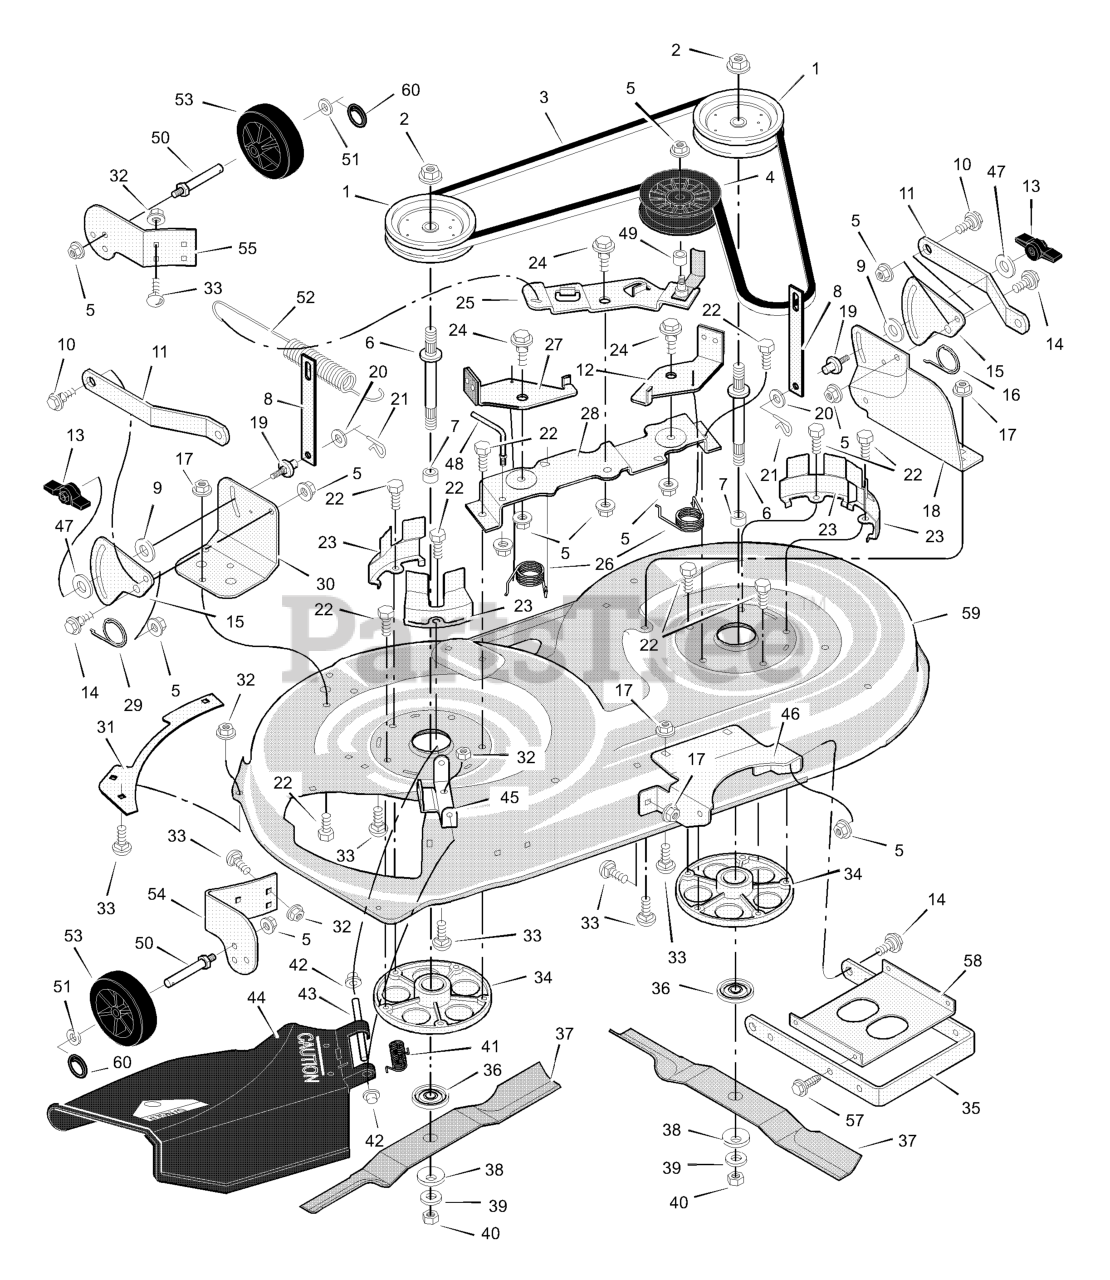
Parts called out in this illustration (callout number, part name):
1	Pulley, Jackshaft
2	Nut, Hex
3	Belt, Mower Drive
4	Pulley, Idler
5	Nut, Flange
6	Jackshaft
8	Link, Lift
9	Pad, Friction
10	Bolt, Shoulder
11	Bracket, Suspension
12	Pad Assembly, Left Brake
13	Knob
14	Bolt, Shoulder
15	Plate, Suspension
17	Nut, Flange
18	Bracket, Suspension
19	Pin, Hanger
21	Pin, Hair
22	Bolt
23	Cover, Pulley
24	Bolt, Shoulder
25	Arm, Idler
27	Pad Assembly, Right Brake
28	Bracket, Brake
30	Bracket, Suspension
32	Nut, Flange
33	Bolt, Carriage
34	Mandrell Housing
35	Bracket, Suspension
36	Adapter, Blade
42	Cap, Push On
43	ROD, Deflector
44	Deflector Assembly
45	Bracket, Deflector Hinge
46	Bracket, Front Hanger
48	Guide, Belt
50	BOLT, Gauge Wheel
52	Spring, Extension
53	Wheel, Gage
54	Bracket, Right Wheel
55	Bracket, Left Wheel
58	Stiffener
59	Housing, Blade, Complete (NO LONGER AVAILABLE)
59	Housing, Blade (Housing Only)
60	Ring, Locking
